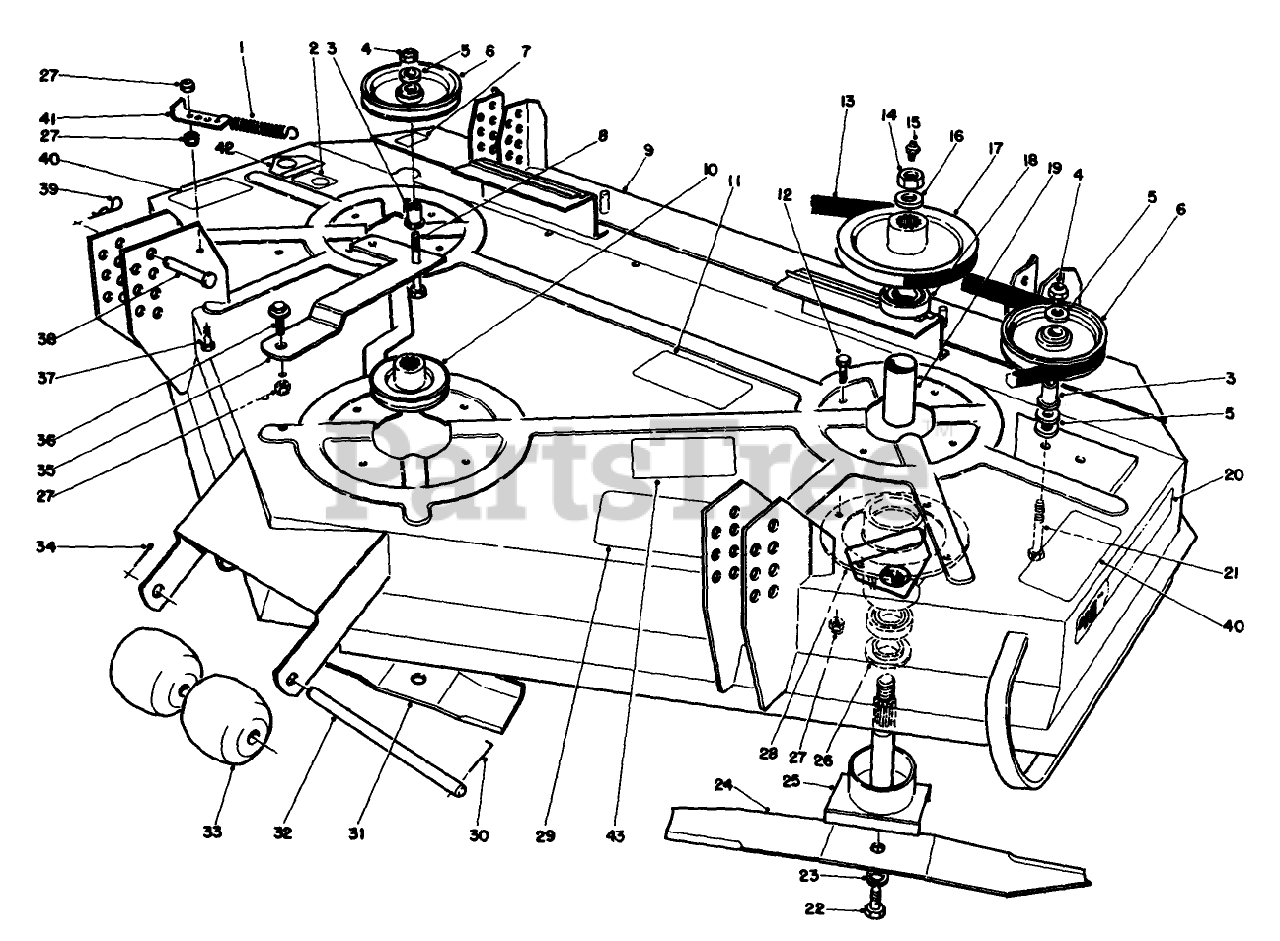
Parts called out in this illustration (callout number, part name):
1	SPRING-EXTENSION, DECK
2	DECAL-NO STEP
3	BUSHING-PULLEY
4	NUT-LOCK, NI
5	WASHER-FLAT
6	PULLEY-IDLER
7	DECAL-LEVEL, NOISE
8	SCREW-HH
9	Deck W.A.
10	CENTER PULLEY
11	DECAL - BELT ROUTING
12	SCREW-HH
13	V-BELT (72)
14	NUT-HEX
15	FITTING-GREASE
16	WASHER
17	OUTSIDE PULLEY
18	BEARING-BALL
19	SPACER-BEARING
20	DECAL - 48"
21	SCREW-HH
22	SCREW-BLADE
23	WASHER-LOCK
24	L/H BLADE
25	SHAFT-SPINDLE
26	SPACER-SPINDLE
27	NUT-LOCK, NI
28	HOUSING-SPINDLE
29	DECAL-TORQUE
30	PIN-SPECIAL
31	CENTER BLADE
32	SHAFT-ROLLER
33	ROLLER
34	PIN-COTTER
35	IDLER LEVER WA R
36	SCREW-SHOULDER
37	SCREW-HH
38	PIN-CLEVIS
39	PIN-HAIR
40	DECAL - DANGER
41	ANCHOR SPRING R
42	DECAL-DANGER
43	DECAL - WARNING
